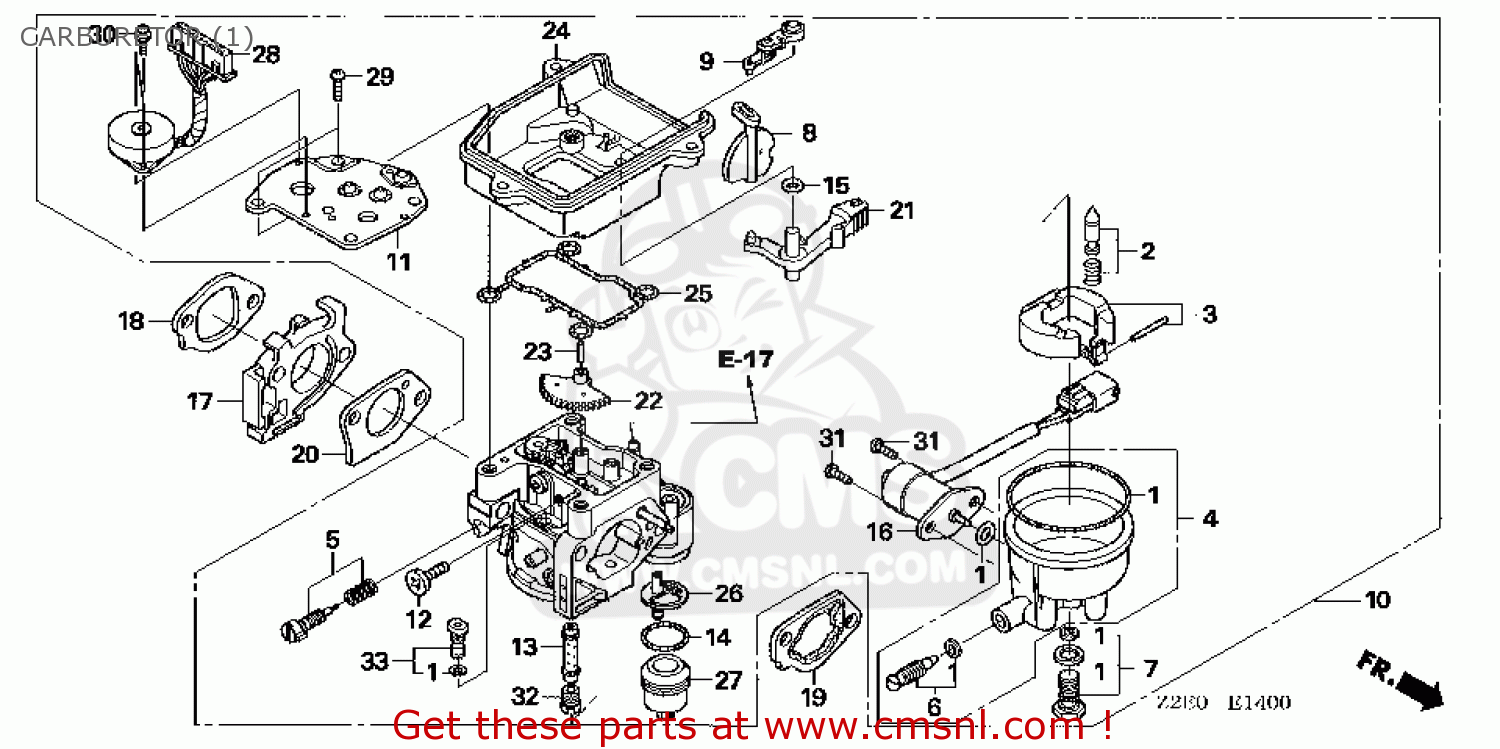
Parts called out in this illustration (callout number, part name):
001	GASKET SET
002	VALVE SET,FLOAT
003	FLOAT SET
004	FLOAT CHAMBER SET
005	SCREW SET
006	SCREW SET,DRAIN
007	SCREW SET
008	CHOKE SET
009	ARM COMP,CHOKE
010	CARBURETOR ASSY(S
011	PLATE,MOTOR
012	SCREW,THROT STOP
013	MAIN NOZZLE
014	O-RING , FUEL STRAIN
015	O-RING
016	VALVE ASSY,SOLENO
017	INSULATOR,CARB
018	PKG,INSULATOR
019	SPACER COMP,CARB
020	PACKING,CARBURETO
021	LEVER,CHOKE
022	GEAR,MIDDLE
023	SHAFT,GEAR CENTER
024	CASE,MOTOR
025	PKG,MOTOR CASE
026	FILTER,CUP
027	CUP,FUEL STRAINER
028	MOTOR COMP,TH CON
029	SCREW,PAN,5X20
030	SCREW-WASHER3X6
031	SCREW-WASHER,5X12
032	JET,MAIN #108
033	JET SET,PILOT,#45
